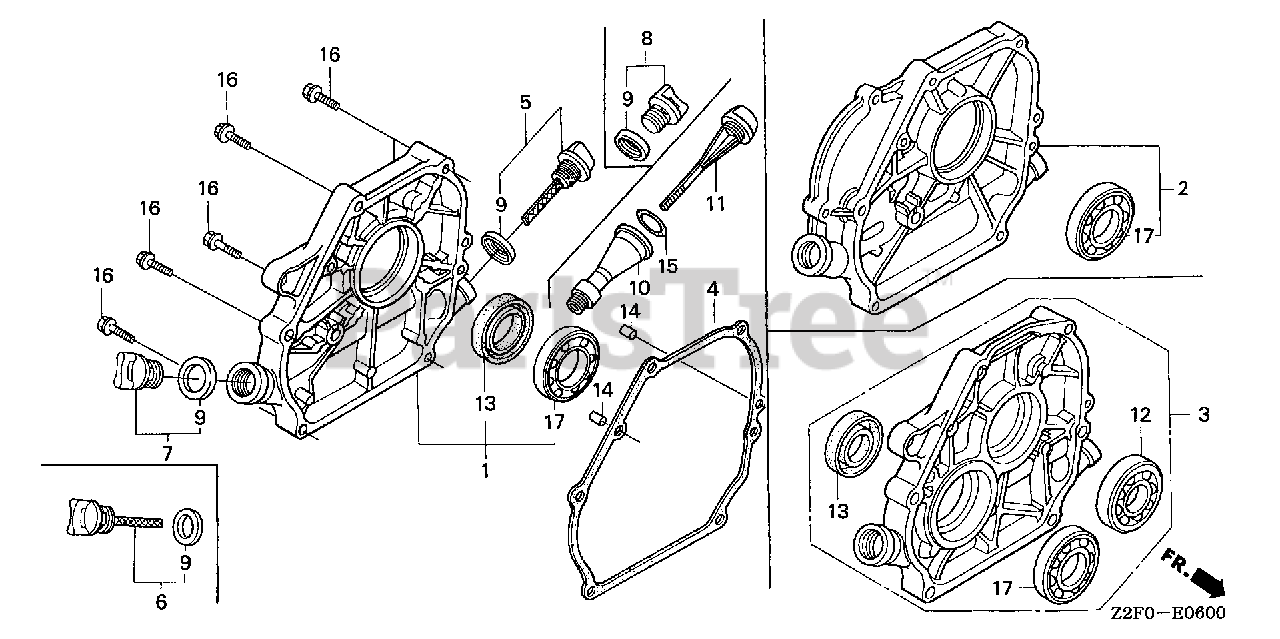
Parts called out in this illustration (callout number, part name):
1	COVER ASSY., CRANKCASE
4	GASKET, CASE COVER (NON-ASBESTOS)
5	CAP ASSY., OIL FILLER (GRAY)
7	CAP ASSY., OIL FILLER
9	GASKET, OIL FILLER CAP
13	OIL SEAL (25X41X6) (NOK)
14	PIN, DOWEL (8X14)
16	BOLT, FLANGE (8X32)
17	BEARING, RADIAL BALL (6205)
